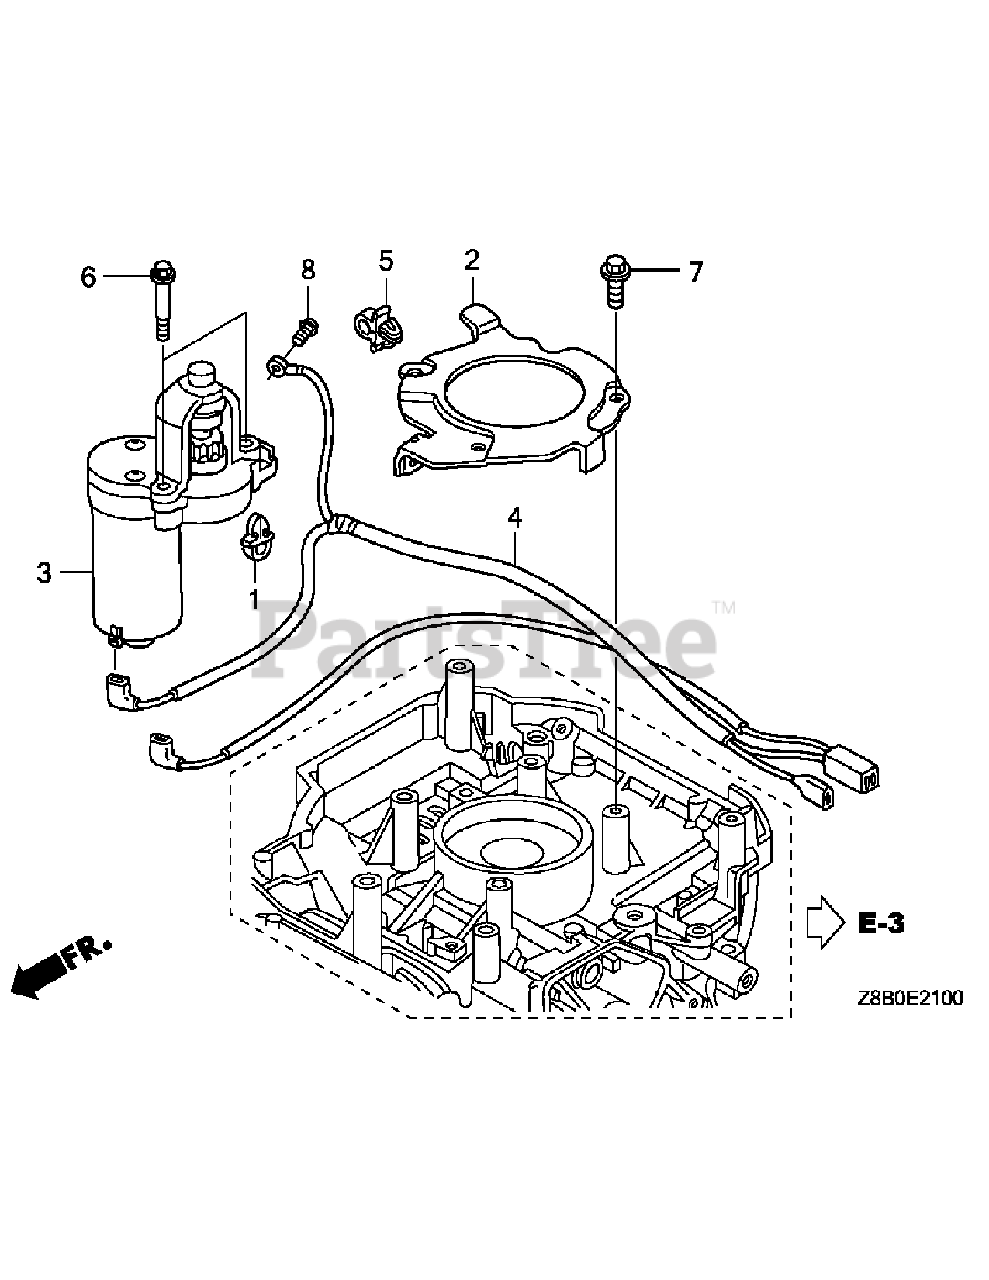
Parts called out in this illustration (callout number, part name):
1	HOLDER, WIRE
2	CLAMPER, CORD
3	MOTOR ASSY., STARTER
4	CORD, TERMINAL EARTH
5	HOLDER, WIRE (FASTEX)
5	CLIP A, CABLE (NIFCO)
6	BOLT, SPECIAL, 6MM
7	BOLT, FLANGE, 6X12(CT200)
8	SCREW, PAN, 5X8
